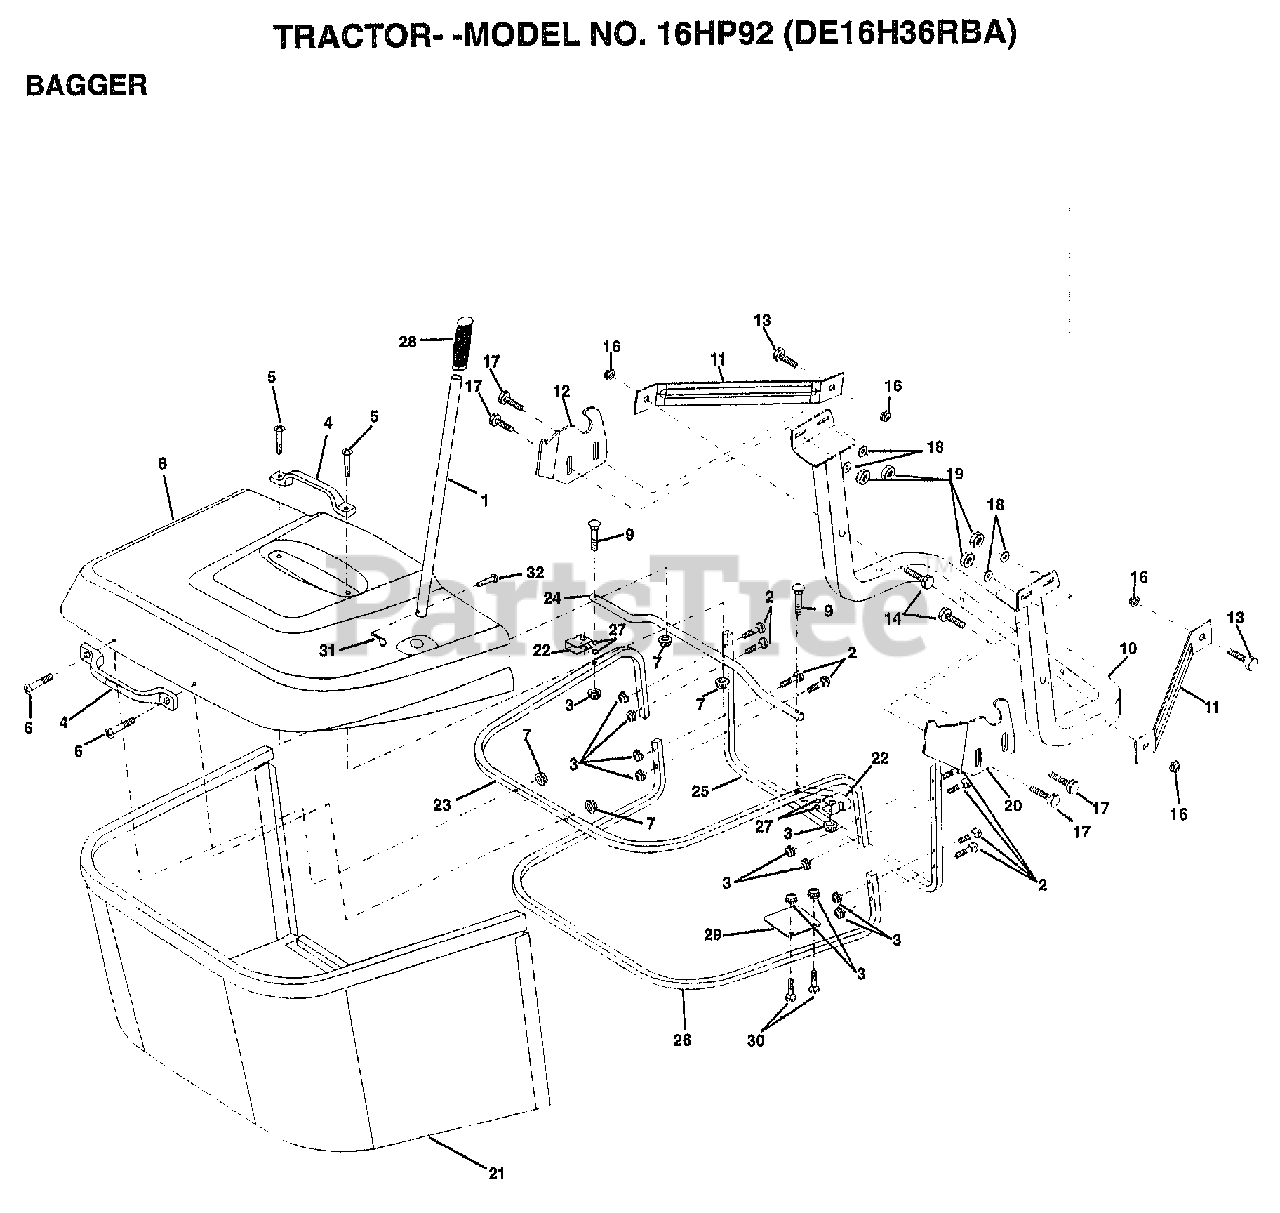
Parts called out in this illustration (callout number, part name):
1	TUBE.HDLE.BAG.CRD
2	BOLT.CARRIAGE.1/4-20X2.0
4	HANDLE.GRAB.BLACK.
5	"SCREW,PAN.HEAD"
7	NUT.WIZ.LOCK
8	COVER.BAGGER.CRD
9	BOLT CARRIAGE
10	SUPT.ASM.WLDMNT.BAG.CRD
11	BRKT.SUPT.UPPER.BAG.CRD
12	BRKT.PIVOT.BAG.LH.CRD
13	BOLT
14	BOLT.HEX.3/8-16X2-1/2
17	BOLT
18	WASHER
19	NUT
20	"BRKT.PIVOT.BAG,RH.CRD"
21	BAG.ASM.CRD
22	BRKT.SIDE.BAG.CRD
23	TUBE.UPPER.BAG.CRD
24	TUBE.PIVOT.BAG.CRD
25	TUBE.FT.BAG.CRD
26	TUBE.LOWER.BAG.CRD.
27	GROMMET.EXTRUDED
28	GRIP.HANDLE.BLACK
29	PLATE.STOP.BAG.HDLE.CRD
30	BOLT.CARRIAGE
31	RETAINER M
32	RIVET.DRILL.1.75
